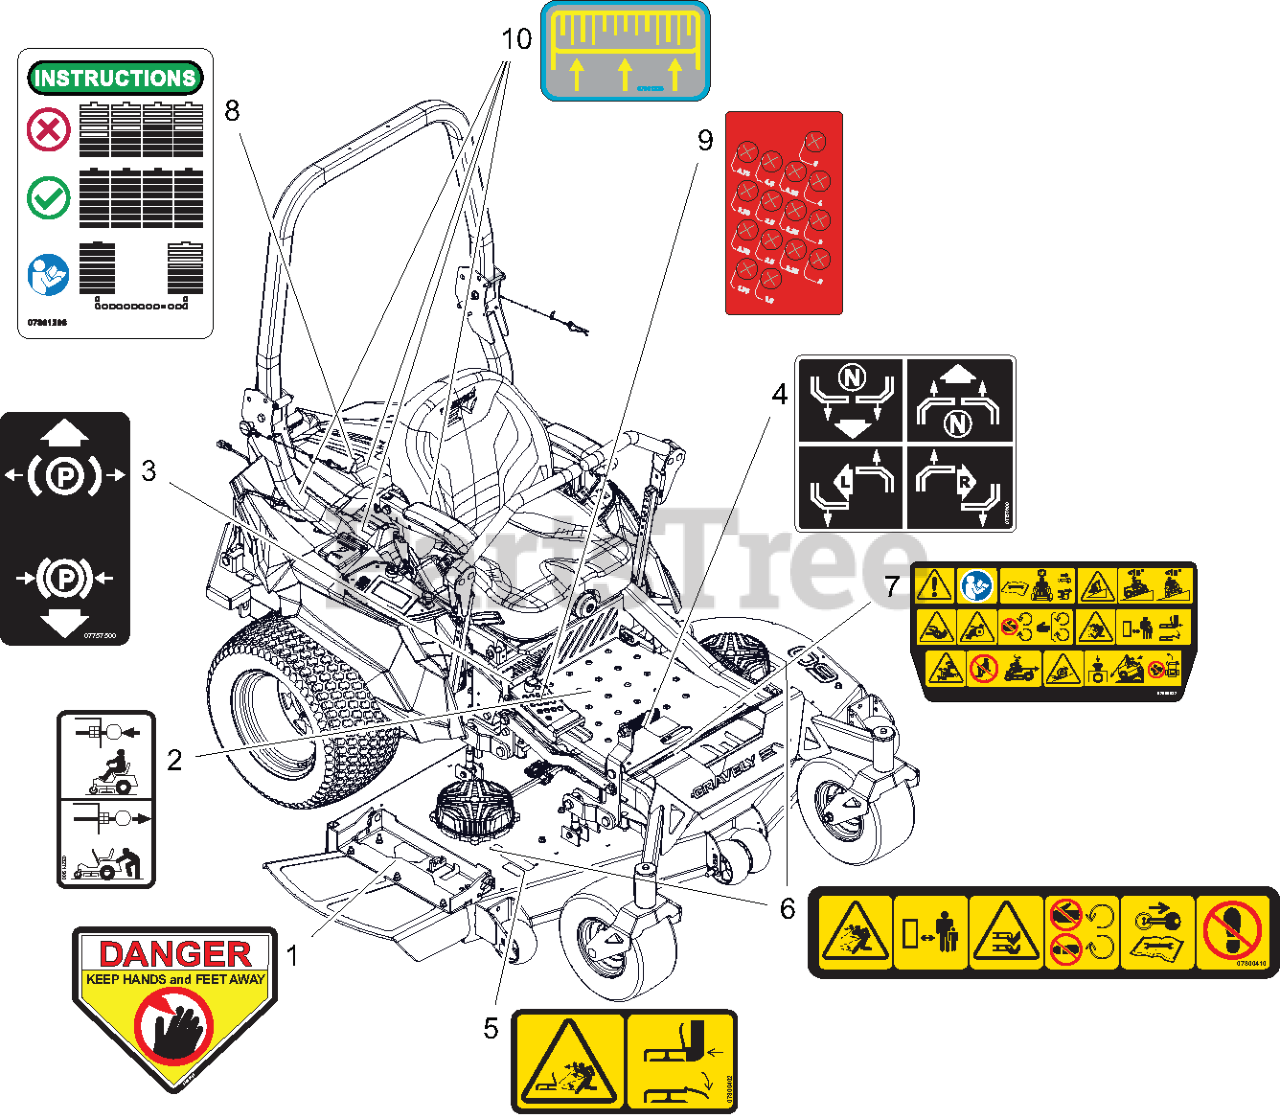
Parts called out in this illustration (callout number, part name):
1	DECAL, DANGER
2	DECAL, TRANSMISSION DISCONNECT
3	DECAL, PARKING BRAKE LEVER
4	DECAL, INSTRUCTIONAL-STEERING
5	DECAL, SAFETY - DECK GUARDING
6	DECAL, DECK SAFETY
7	DECAL, MAIN SAFETY
8	DECAL, BATTERY BALANCE
9	DECAL, HEIGHT OF CUT
10	DECAL, BATTERY INSTALL DIRECTION
